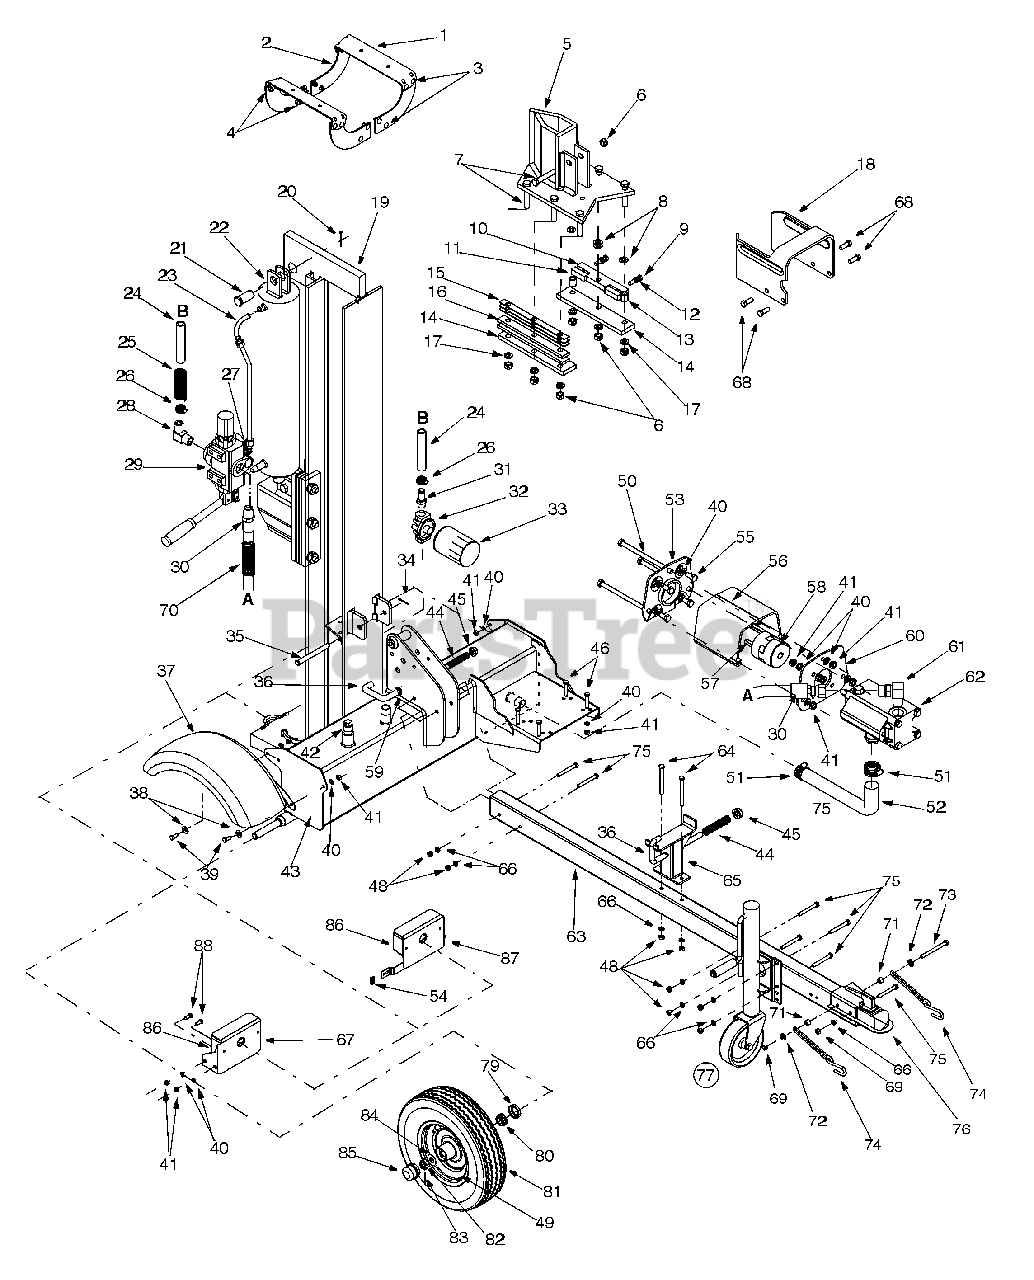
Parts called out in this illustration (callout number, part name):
4	Flanged Lock Nut, 3/8-16
7	Hex Head Screw, 1/2-20 x 2.75
8	Flat Washer, .531 ID x .94 OD
9	Hex Cap Screw, 3/8-24 x 1.5
11	Adjustable Gib, 5/8 x 5/8 x 2
12	Hex Jam Nut, 3/8-24
13	Spacer
17	Lock Washer, 1/2
21	Clevis Pin
22	Kit Seal 5.0" for Best Metals cylinder 718-0313
22	Hydraulic Cylinder
22	Kit Seal 5.0" for XINGHUI cylinder 718-0313A
22	Kit Seal 5.0" for ENERGY cylinder 718-0313A
23	Hydraulic Tube
24	Return Hose, 3/4 x 44 Lg
25	Hose Guard
26	Hose Clamp
27	Tube Adapter
28	Return Elbow
30	High Pressure Hydraulic Hose
32	Filter Head
33	Oil Filter
34	Cotter Pin
35	Hinge Pin
36	Locking Rod
39	Hex Cap Screw, 5/16-24 x .75
40	Lock Washer, 5/16
41	Hex Nut, 5/16-24
42	Pipe Plug
46	Hex Cap Screw, 5/16-24 x 1.75
48	Hex Nut, 3/8-16
49	Rim / Tire Assembly
50	Hex Cap Screw, 5/16-24 x 5.25
51	Hose Clamp
52	Suction Hose
54	Speed Clip
55	Hex Cap Screw, 5/16-24
56	Coupling Shield
57	Key, 1/4 x 2.00
57	Key, 3/16 x .75
58	Flexible Coupling, 1.00 x .4375
59	Flat Washer, .63 x .93 x .060
62	Gear Pump, Hyd (16 GPM)
62	Pump Kit
62	Gear Pump, Hyd (15 GPM)
64	Hex Screw, 3/8-16 x 4.0
69	Hex Lock Nut, 3/8-16
70	Hose Guard
72	Flat Washer, 3/8" ID x .87" OD
73	Hex Bolt, 3/8-16 x 4.25
74	Chain
75	Hex Bolt, 3/8-16 x 3
76	Hitch Coupler
77	Adjustable Jack Stand Assembly
79	Bearing Seal
80	Tapered Bearing
81	Wheel Assembly
82	Slotted Nut, 3/4-16
83	Cotter Pin
84	Flat Washer, .760 ID x .500 OD
86	Taillight Assembly
